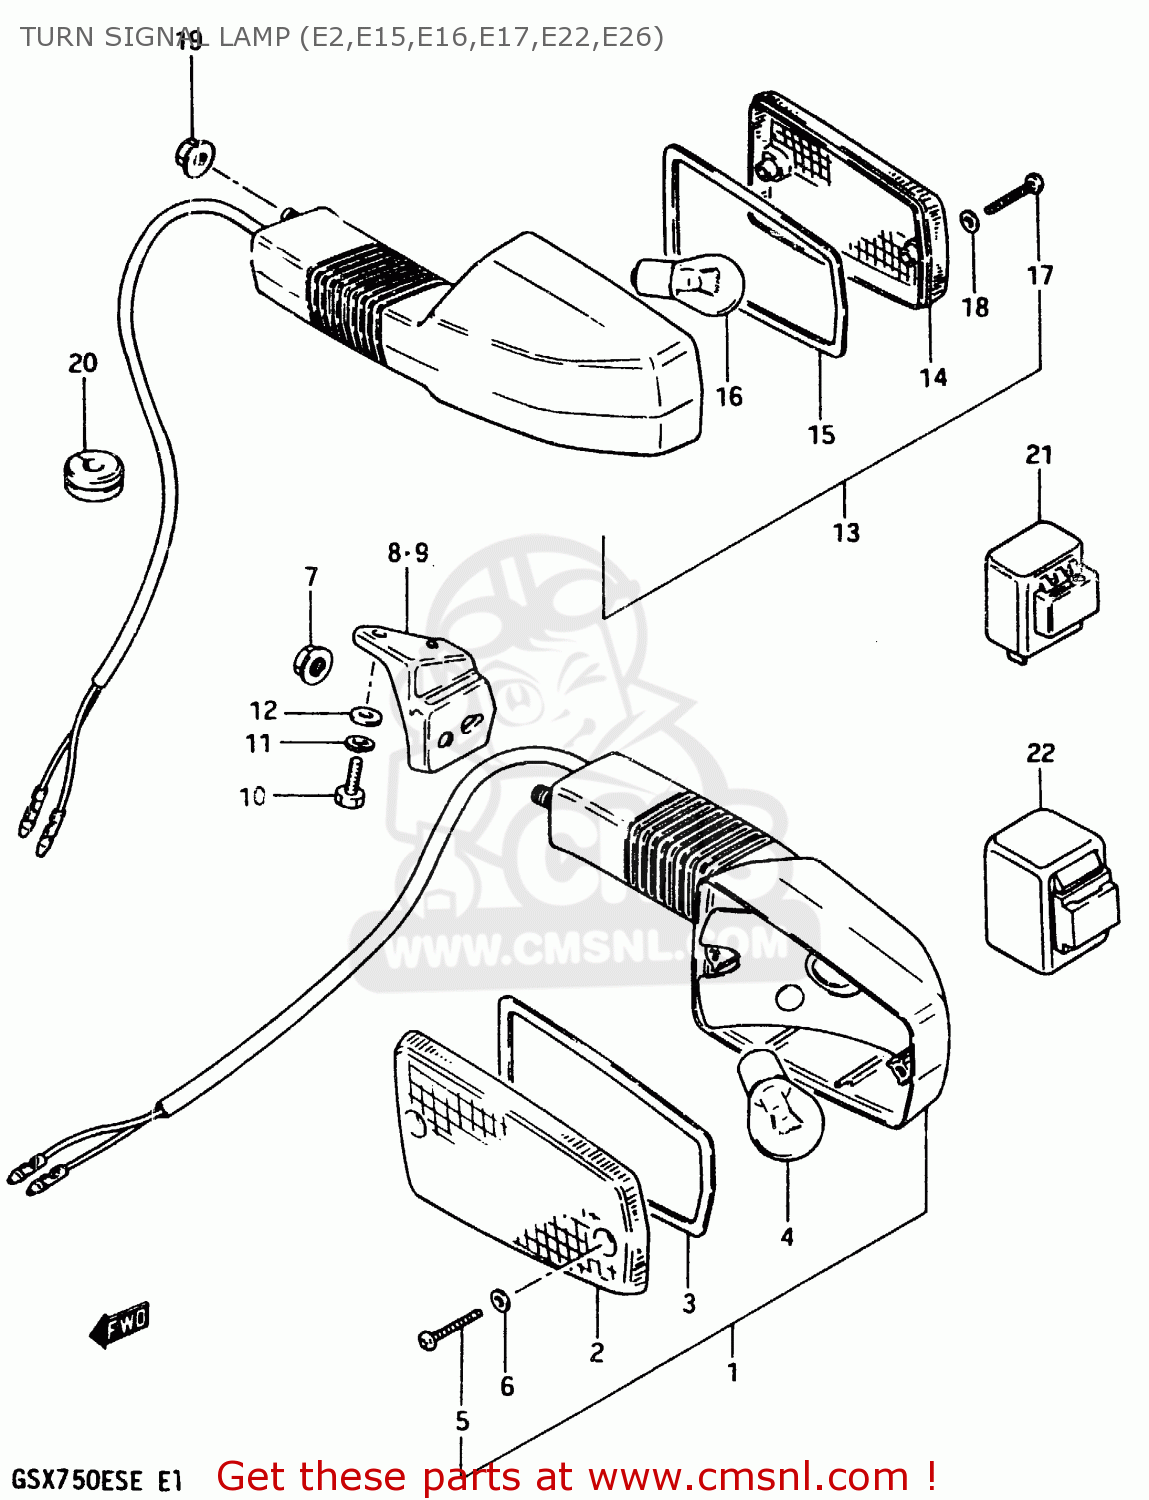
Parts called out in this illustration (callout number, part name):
1	LAMP ASSY, FRONT TURN SIGNAL
2	LENS
3	GASKET (NAS)
4	BULB(12V21W)
5	SCREW
6	GASKET (NAS)
7	NUT
8	BRACKET,FRONT TURN SIGNAL
9	BRACKET,FRONT TURN SIGNAL
10	BOLT
11	LOCK WASHER
12	WASHER,8.5X16X
13	LAMP ASSY, REAR TURN SIGNAL
14	LENS,TURN SIGN
15	GASKET (NAS)
16	BULB(12V21W)
17	SCREW
18	GASKET (NAS)
19	NUT
20	GROMMET
21	RELAY ASSEMBLY,TURN SIGNAL
22	RELAY ASSY,TUR
